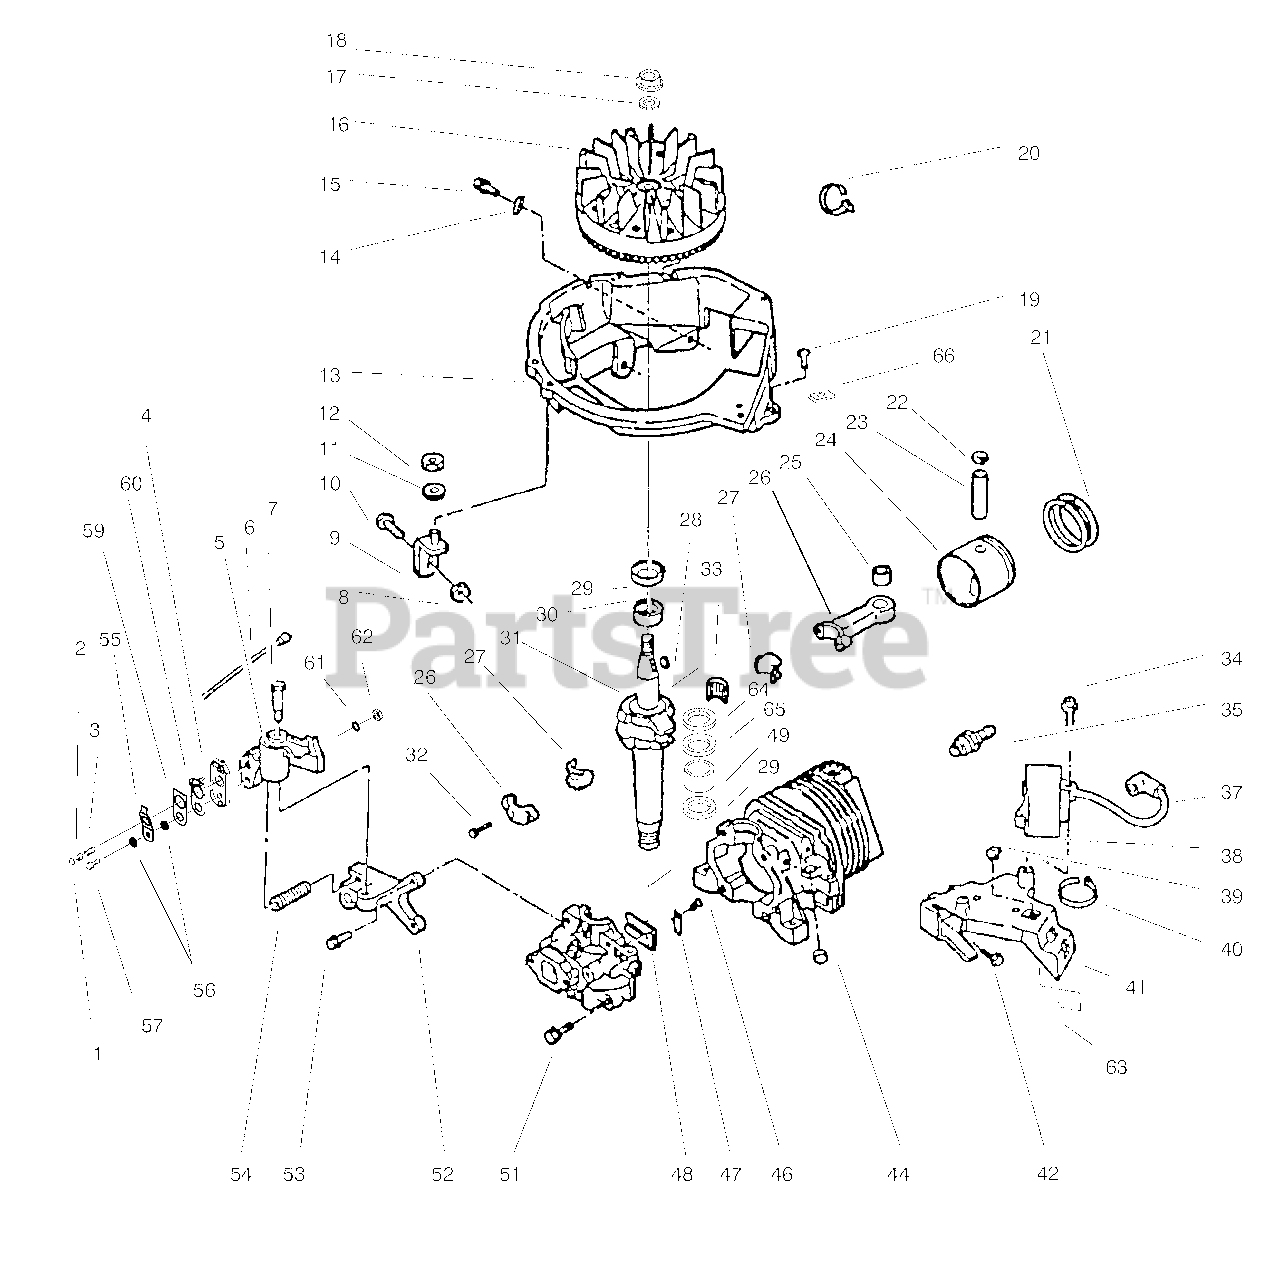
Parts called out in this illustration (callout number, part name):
1	Retainer
2	Actuator-Brake Lever
3	Spring-Cable, Return
4	Case-Switch
5	Assembly-Brake
6	Wire Lead
7	Bolt-Shoulder
9	Assembly-Brace
11	Washer
13	Shroud-Base
14	Clip-"J"
16	Assembly-Flywheel
17	Washer-Lock
18	Nut-Flywheel
20	Tie Strap
21	Set-Ring
22	Ring-Retaining
23	Pin-Wrist
24	Set-Piston & Ring (Incl. Ref.# 21-23)
25	Assembly-Bearing
26	Assembly-Conn. Rod (Incl. Ref. #25, 27, 32, & 33)
27	Liner-Pair
28	Key-Flywheel
29	Seal-Oil
30	Bearing-Main
31	Crankshaft
33	Strip-Roller
34	Screw
35	Spark Plug
37	Wire Lead
38	C. D. Ignition Module (Incl. Ref. #37)
39	Grommet
40	Tie Strap
41	Bracket-C. D.
47	Plate-Reed
49	Bearing-Main
52	Bracket-Brake
54	Spring-Brake
56	Washer
57	Screw-Hex Hd. Cap
60	Plate-Contact
61	Washer-Lock
62	Nut
63	Bolt-Carriage
64	Bearing-Thrust
65	Washer-Thrust
66	Nut-Speed
